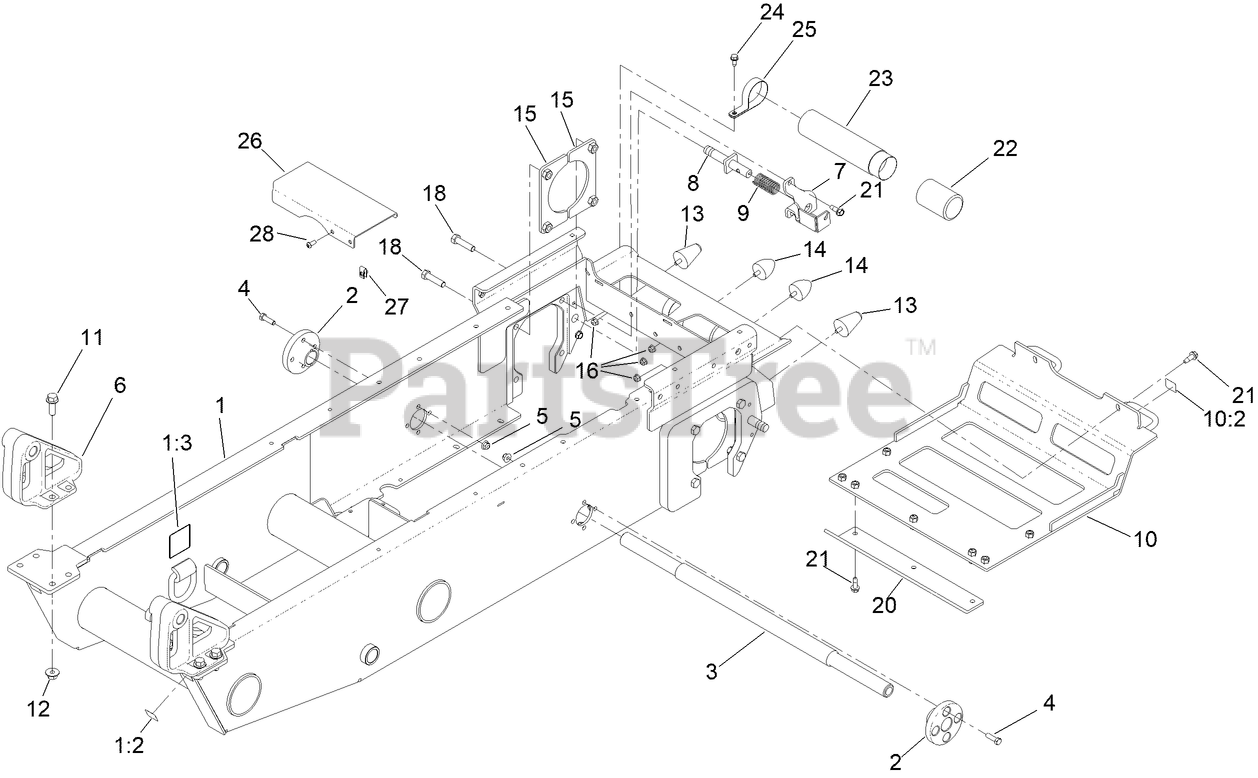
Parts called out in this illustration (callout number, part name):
1	FRAME ASM- STRAIGHT
1:2	DECAL-LIFT HERE
1:3	DECAL-TIEDOWN
2	HUB-MOUNT, TRACK
3	SHAFT-TRACK
4	SCREW-HH
5	NUT-HF, NI
6	PIVOT-DUMP
7	BRACKET-BRAKE
8	SHAFT-BRAKE
9	SPRING-COMPRESSION
10	PLATE-SIDE
10:2	DECAL-TIEDOWN
11	SCREW-HHF
12	NUT-LOCK, FLANGE
13	BUMPER-RUBBER
14	BUMPER-RUBBER
15	HYDRO MOUNTING PLATE ASM
16	NUT-HF, NI
18	SCREW-HH
20	PLATE-SKID
21	SCREW-TAPPING
22	CAP-HOUSING
23	TUBE-MANUAL
24	SCREW-HWHTF
25	CLAMP-R
26	BRACKET, MANIFOLD SHIELD
27	NUT-CLIP, U
28	SCREW-HSBH
